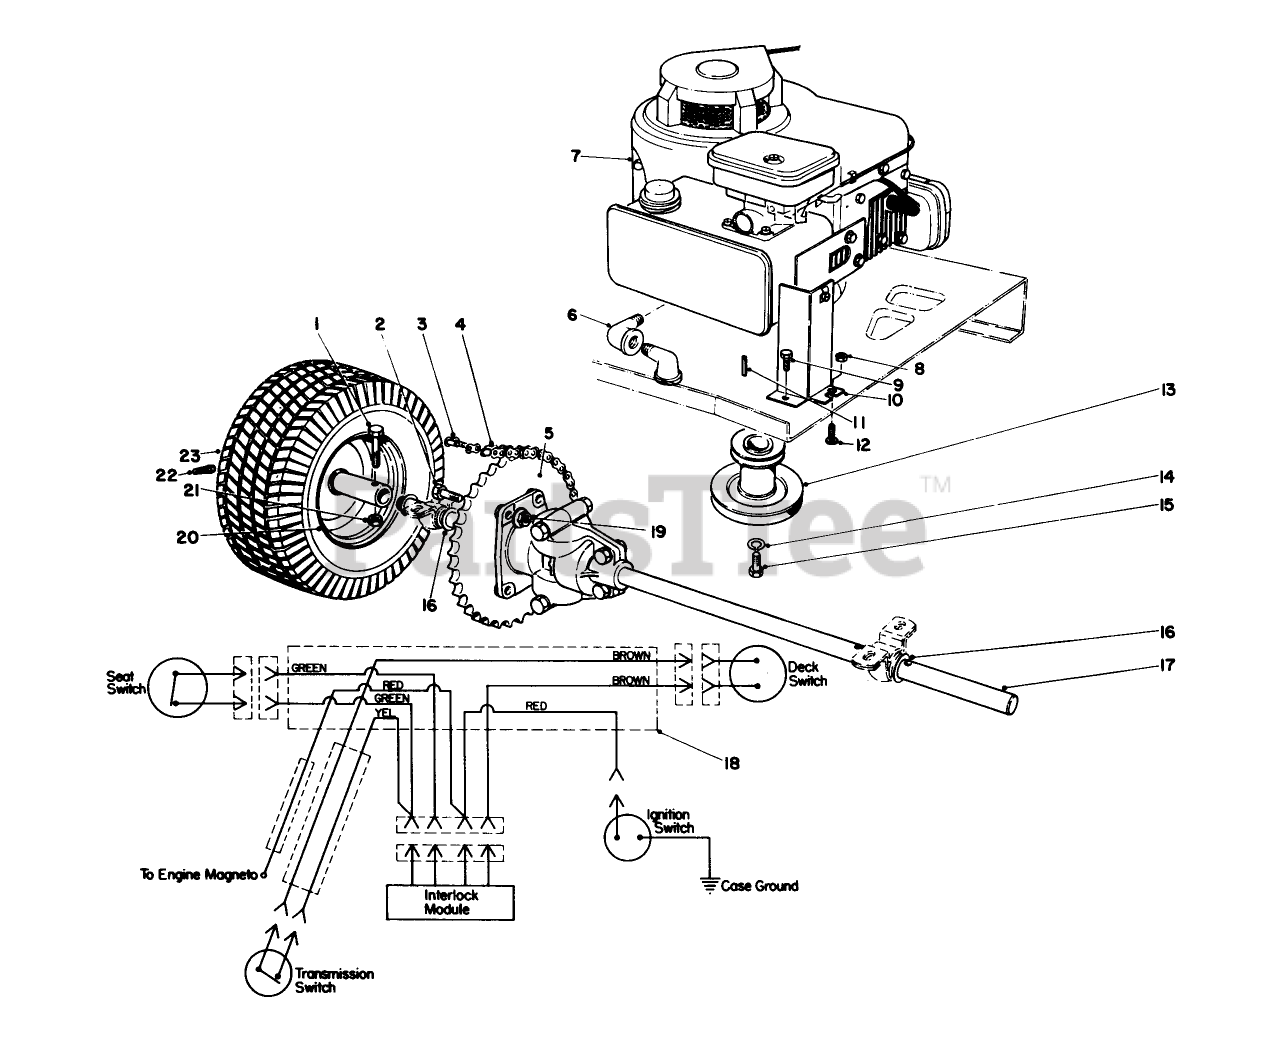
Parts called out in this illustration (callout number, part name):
1	SCREW-HH
2	SCREW-HH
3	LINK-CONNECTING
4	ROLLER CHAIN
5	Sprocket
6	90deg. Street Elbow
7	Engine
8	NUT-KEPS
9	SCREW-HWHTF
10	Support-Wire
12	5/16-18X5/8 TRS HD MS
13	ENGINE SHEAVE
14	WASHER-LOCK
15	SCREW-HH
16	WASHER
17	Differential
18	Wiring Harness
19	NUT-LOCK, CONE
21	NUT-LOCK, CONE
22	STEM-VALVE
23	Tire
